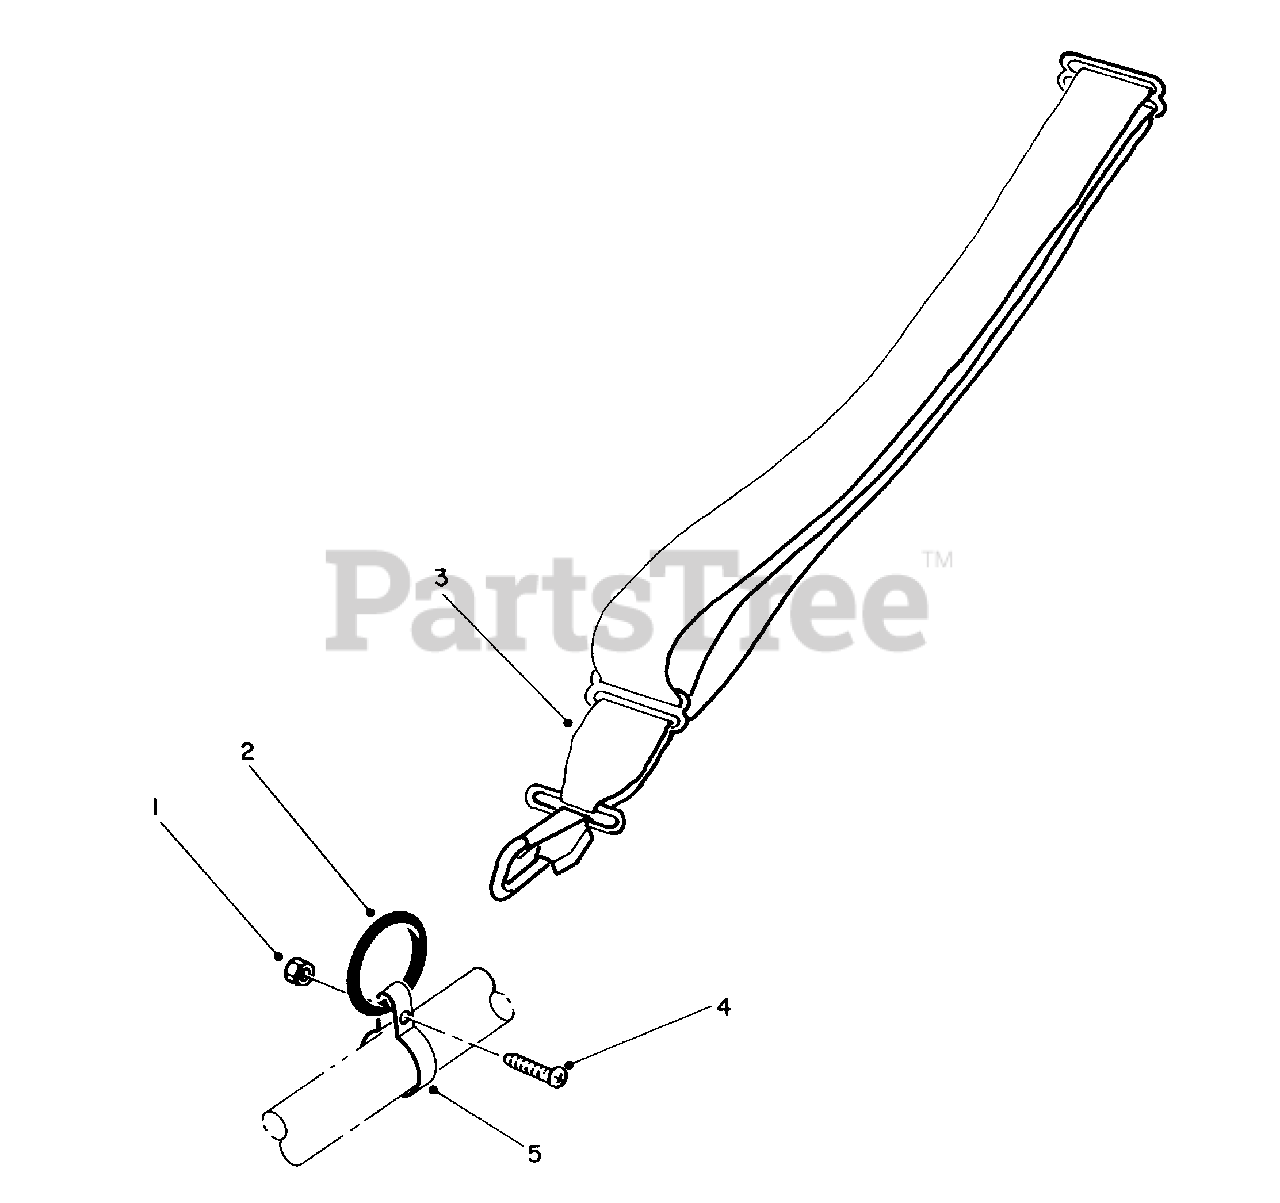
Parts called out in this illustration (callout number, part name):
2	Ring/Harness
4	1-4 Screw
5	Clamp
